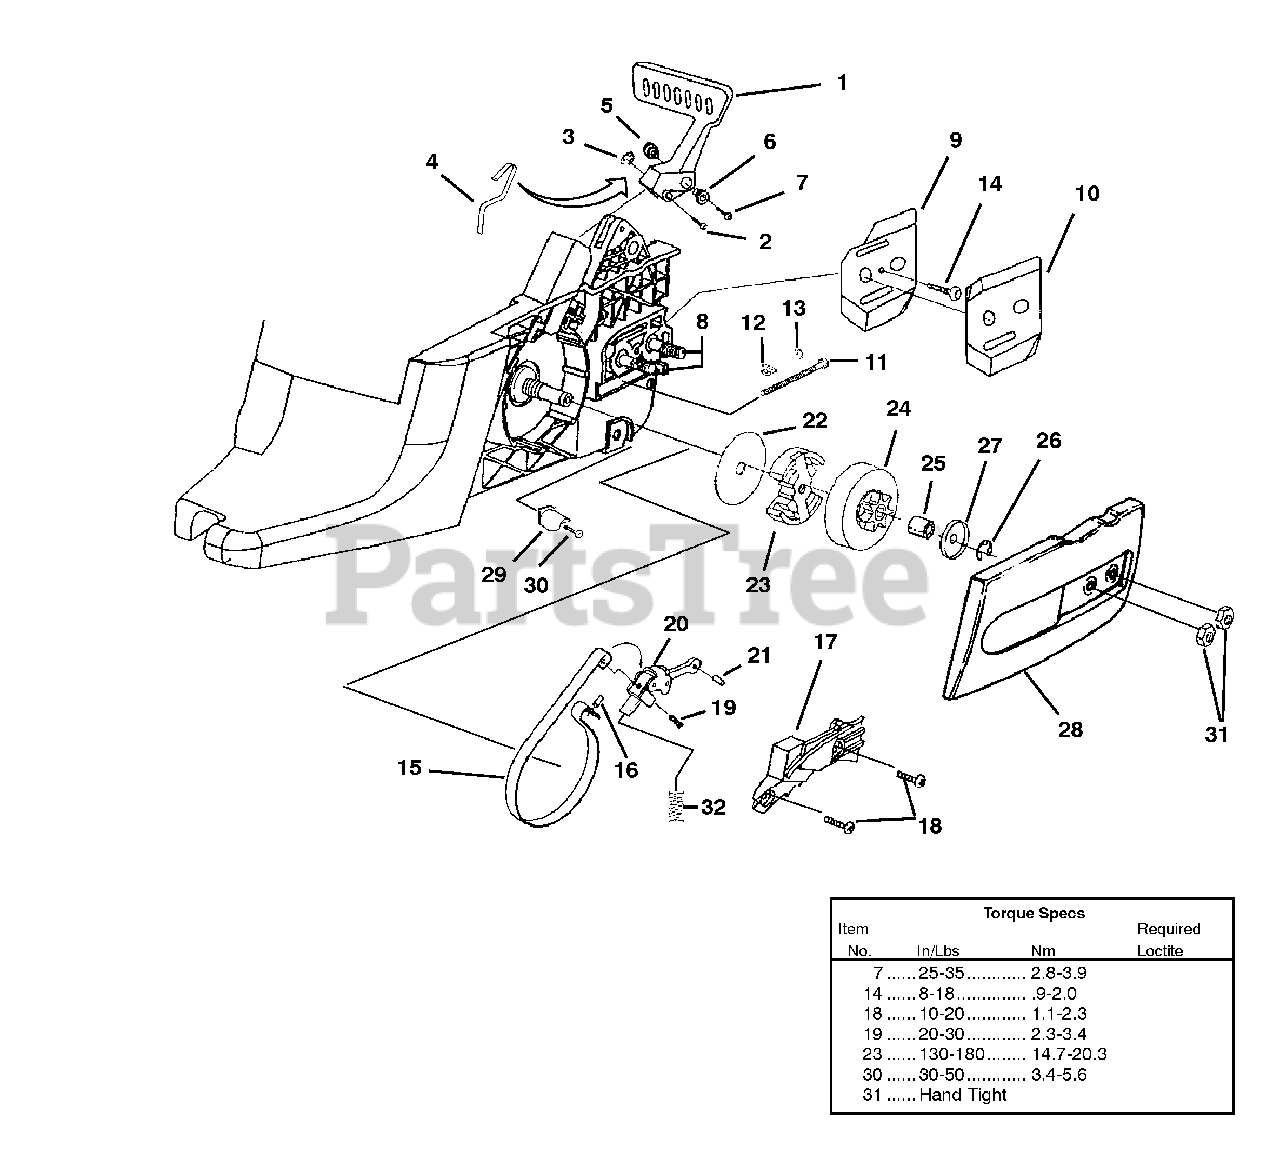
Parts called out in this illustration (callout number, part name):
1	Hand Guard Kit
2	Hand Guard Actuating Pin
3	Retaining Ring
4	Spring, Handguard
5	Pivot, L.H.
6	Pivot, R.H.
7	Screw, Hex Socket Hd. (8-32 x 5/8")
8	Guide Bar Bolt
9	Plate, Guide Bar
10	Plate, Guide Bar
11	Screw, Guide Bar Adjusting
12	Pin, Guide Bar Adjusting
13	Ring, Retaining
14	Screw, Thread Form (6-19 x 1/2")
15	Chain Brake Kit
16	Pin, Roll
17	Cover, Chain Brake
18	Screw, Pan Hd. (6-19 x 1/2")
19	Screw, Pan Hd. (8-16 x .320)
20	Chain Brake Link
21	Pin, Roll
22	Thrust Washer
23	Clutch & Hardware
24	Sprocket, Drum (.325 Pitch)
25	Bearing, Needle
26	Ring, Retaining
27	Washer, Cupped
28	Drive Case Cover
29	Stop, Chain
30	Screw, Thread Form (10-14 x 1/2")
31	Nut, Hex
32	Spring, Compression
